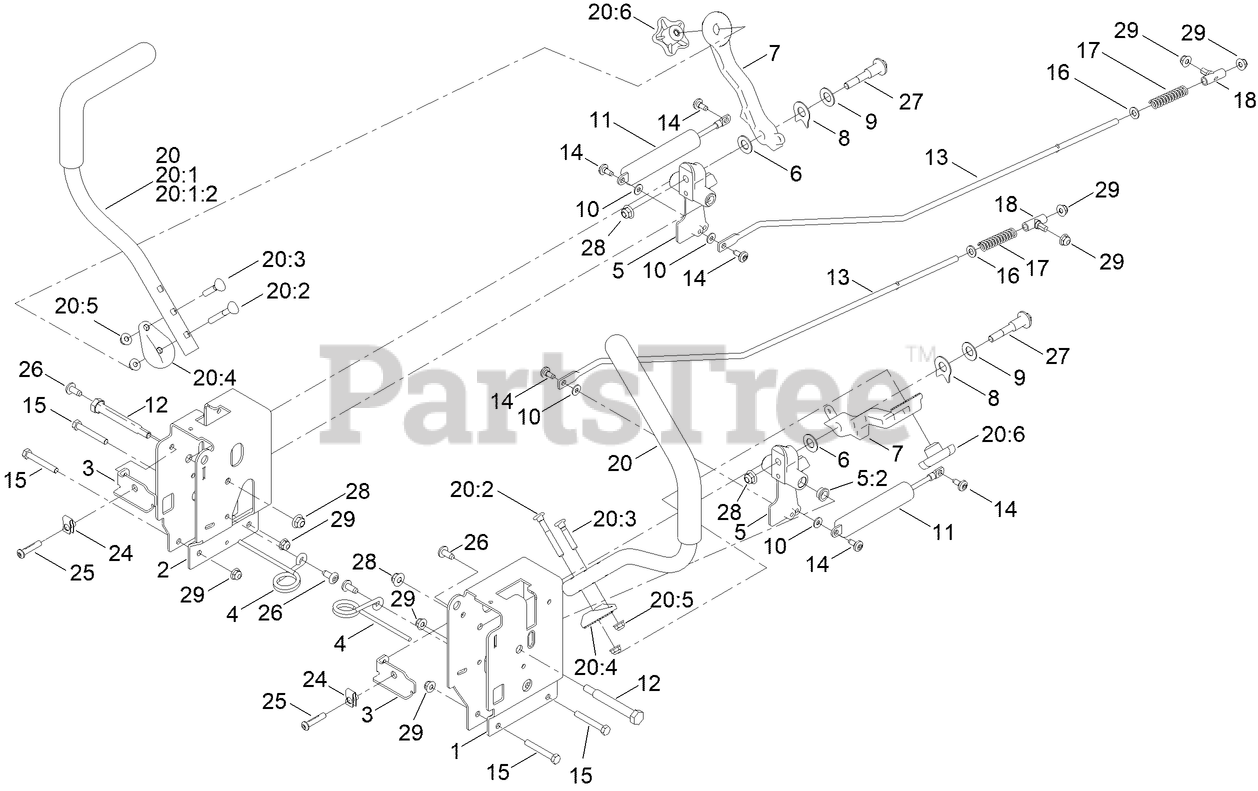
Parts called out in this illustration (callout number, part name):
1	CONTROL BOX - LH G7
2	CONTROL BOX - RH G7
3	ADJUSTMENT PLATE-CONTROL BOX
4	SPRING-TORSION
5	PIVOT ARM ASM
5:2	BUSHING-FLANGE
6	WASHER-NYLON
7	ARM-CONTROL, 32 TEETH
8	SPACER, ANTI-ROTATION
9	WASHER-BELLEVILLE
10	WASHER
11	DAMPER - NON CAVITATING
12	BOLT-PIVOT
13	ROD-HYDRO
14	SCREW-SHOULDER
15	SCREW-HH
16	WASHER-PLAIN
17	SPRING-COMPRESSION
18	MOUNT-ROD, HYDRO
20	HANDLE-CONTROL, ASM
20:1	HANDLE-CONTROL,
20:2	SCREW-HANDLE
20:3	SCREW-HANDLE
20:4	DISC-ADJUSTMENT HANDLE, 32 TEETH
20:5	NUT-HF
20:6	KNOB-HANDLE
25	SCREW-HSBH
27	BOLT-PIVOT
28	NUT-HF, NI
29	NUT-HF
